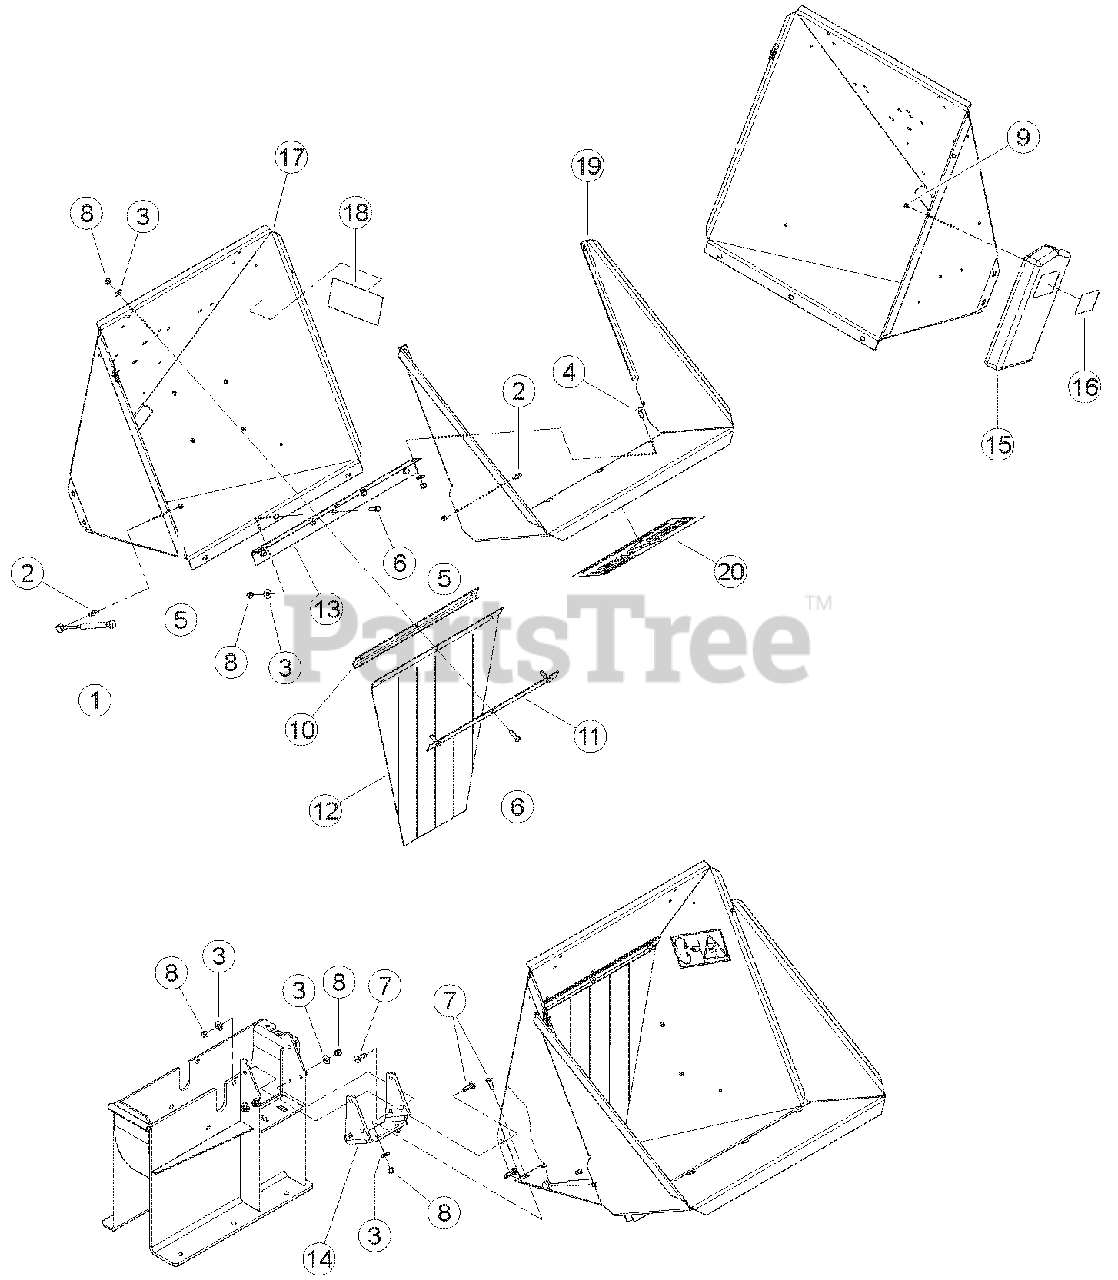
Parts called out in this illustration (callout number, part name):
1	SPRING, GAS 60 PSI
2	STUD, BALL .39
3	WASHER, 3/8 FLAT ZP
4	BOLT, 3/8 X 1 CRG GR5 NC ZP
5	NUT, 5/16 NE NYLOCK ZP
6	BOLT, 3/8 X 1-1/4 HEX HD GR5 ZP
7	BOLT, 3/8 X 1-1/4 CRG GR5 NC ZP
8	NUT, 3/8 NE NYLOCK ZP
9	RIVET, 1/4 X 1/2 DOME HD BLIND SS
10	ANGLE, FLAP ANCHOR
11	STRIP, FLAP RETAINER
12	FLAP, CHIPPER CHUTE
13	HINGE, EXTENSION TRAY
14	BRACKET, CHUTE MOUNT
15	ASSEMBLY, MANUAL CONTAINER SERVICE PART
16	DECAL, MULTILINGUAL MANUAL
17	ASSEMBLY, 5 INCH CHIPPER CHUTE SERVICE PART
18	DECAL, BLADE DANGER ISO
19	ASSEMBLY, 5 INCH EURO CHUTE TRAY SERVICE PART
20	DECAL, BEARCAT WEB
